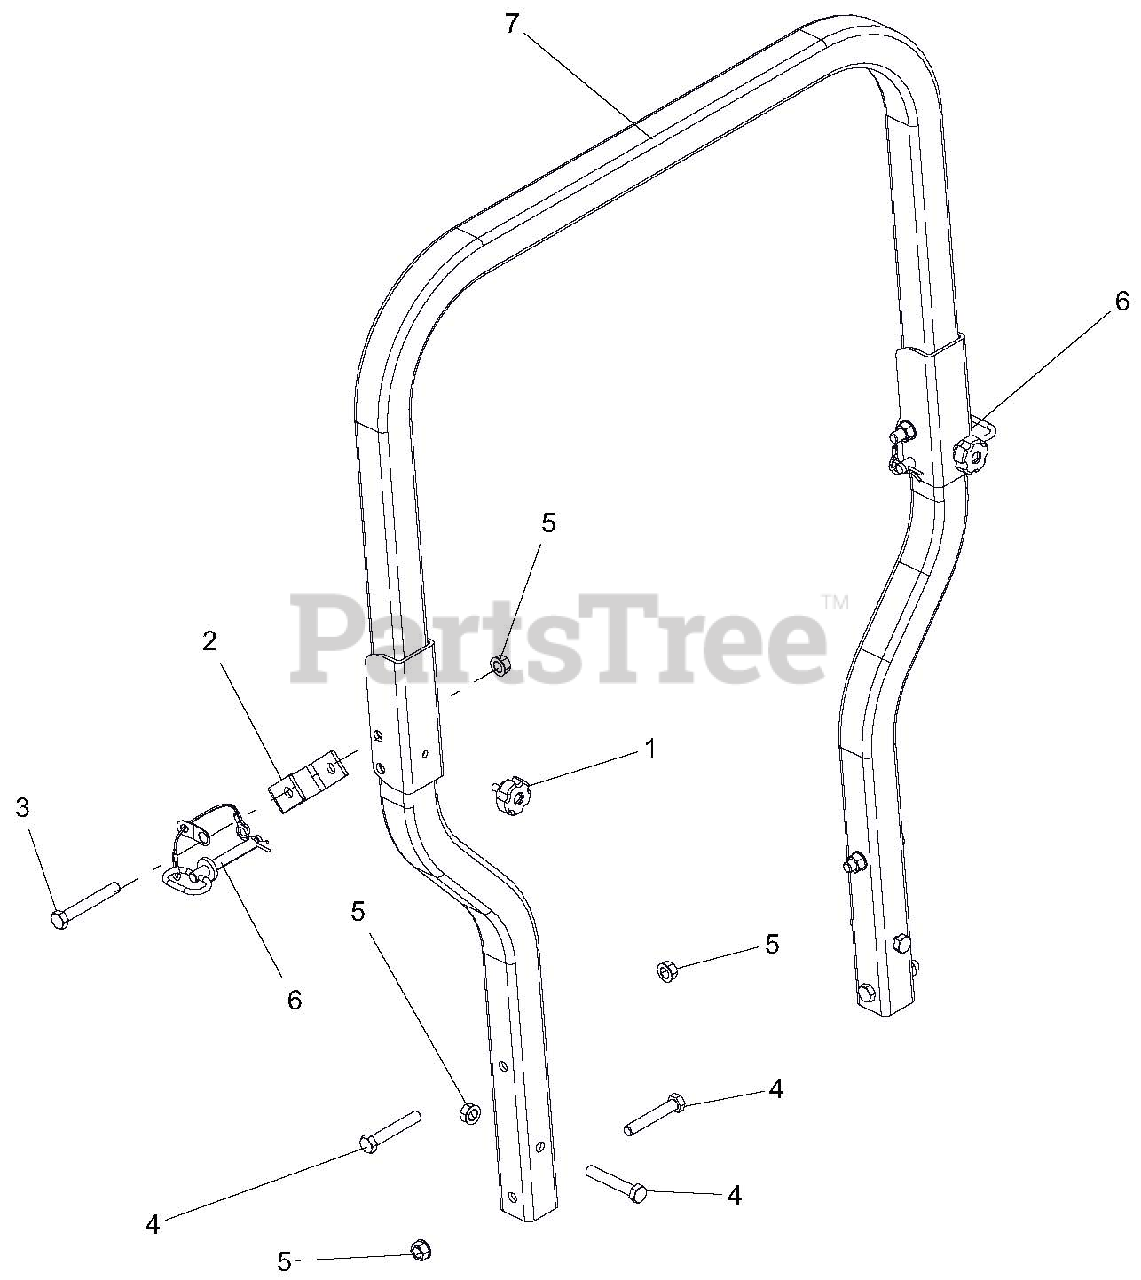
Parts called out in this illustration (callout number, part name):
1	KNOB, ROUND 5/16-18 X .750
2	BRKT, ROPS STOP
3	BLT-HEX .50-13X3.50 GR5 YWZC
4	BLT-HEX .50-13X3.00 GR5 YWZC
5	NUT, LK-TOP-FLG .50-13 YWZC
6	ASSY, ROPS PIN/LANYARD
7	ROPS, PT200 REPLACEMENT
